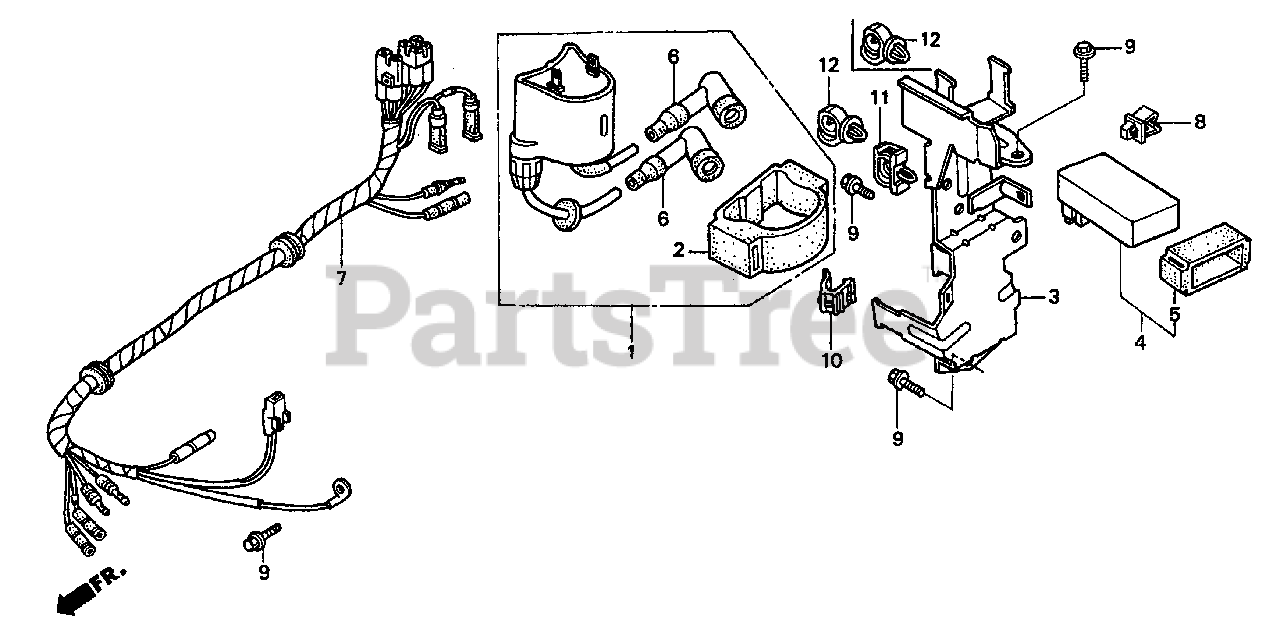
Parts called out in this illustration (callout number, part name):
1	COIL ASSY., IGNITION
2	SUSPENSION, IGNITION COIL
3	BRACKET, IGNITION COIL
4	MODULE ASSY., IGNITION CONTROL (CDI)
4	MODULE, IGNITION CONTROL (CDI)
5	CUSHION, IGNITION CONTROL MODULE
6	CAP ASSY., NOISE SUPPRESSOR
7	WIRE HARNESS ASSY. (NOT AVAILABLE)
8	CLIP B, AIR TEMPERATURE SWITCH WIRE
9	BOLT, FLANGE (6X12)
10	CLIP, WIRE HARNESS
11	CLIP, WIRE HARNESS (10MM)
12	CLIP, WIRE HARNESS (25MM)
